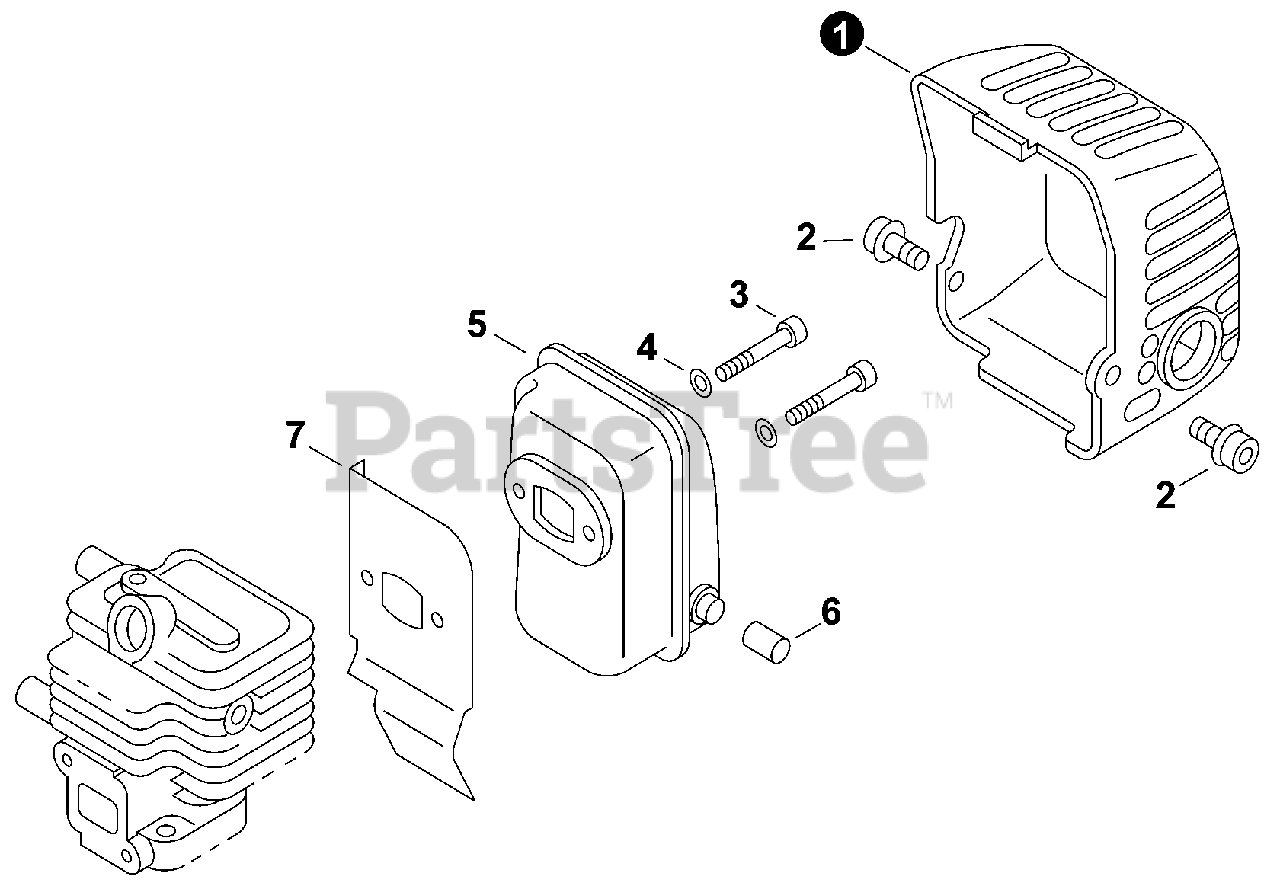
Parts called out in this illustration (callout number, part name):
1	COVER, MUFFLER
2	BOLT 5x8
3	BOLT 5x55
4	WASHER 5.5x12x0.8
6	PIPE, EXHAUST
7	HEAT SHIELD, EXHAUST
